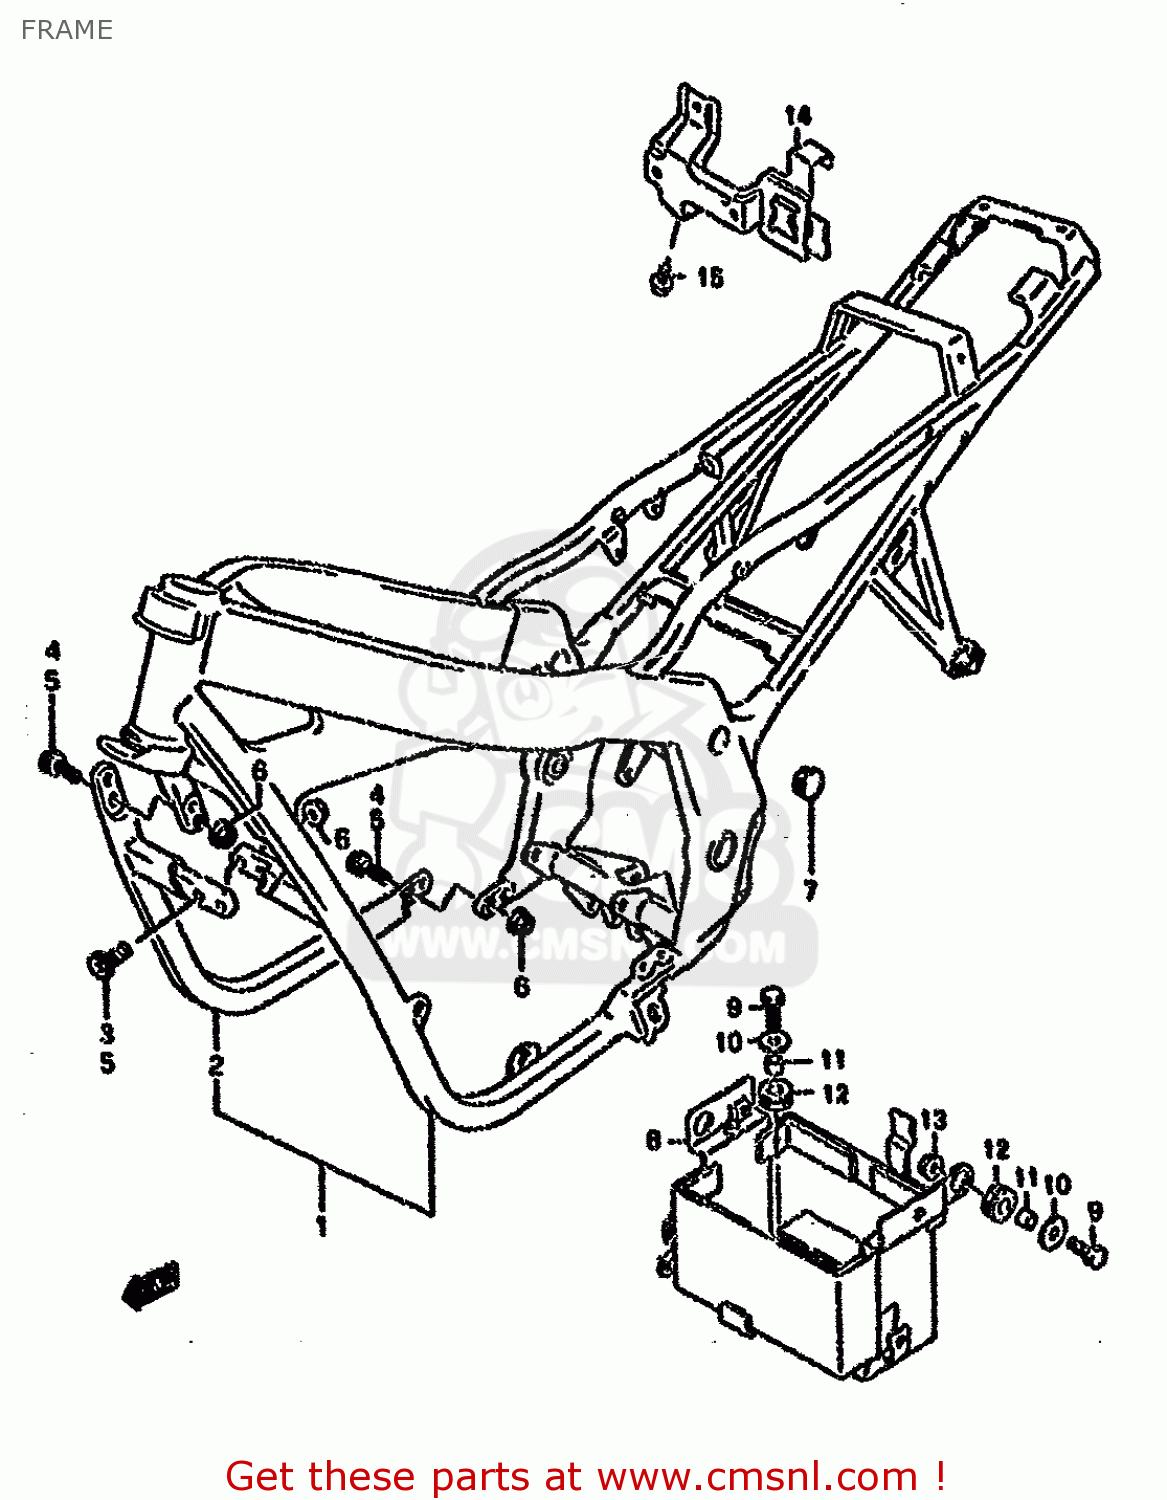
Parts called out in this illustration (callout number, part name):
1	FRAME
2	FRAME SET(GRAY)
3	BOLT
4	BOLT
5	BOLT
6	NUT
7	CAP,BODY FRAME
8	HOLDER,BATTERY
9	BOLT
10	WASHER,COVER,FRONT
11	SPACER(6.2X9X7.5)
12	CUSHION
13	NUT
14	HOLDER,ELECTRIC PARTS
15	BOLT
